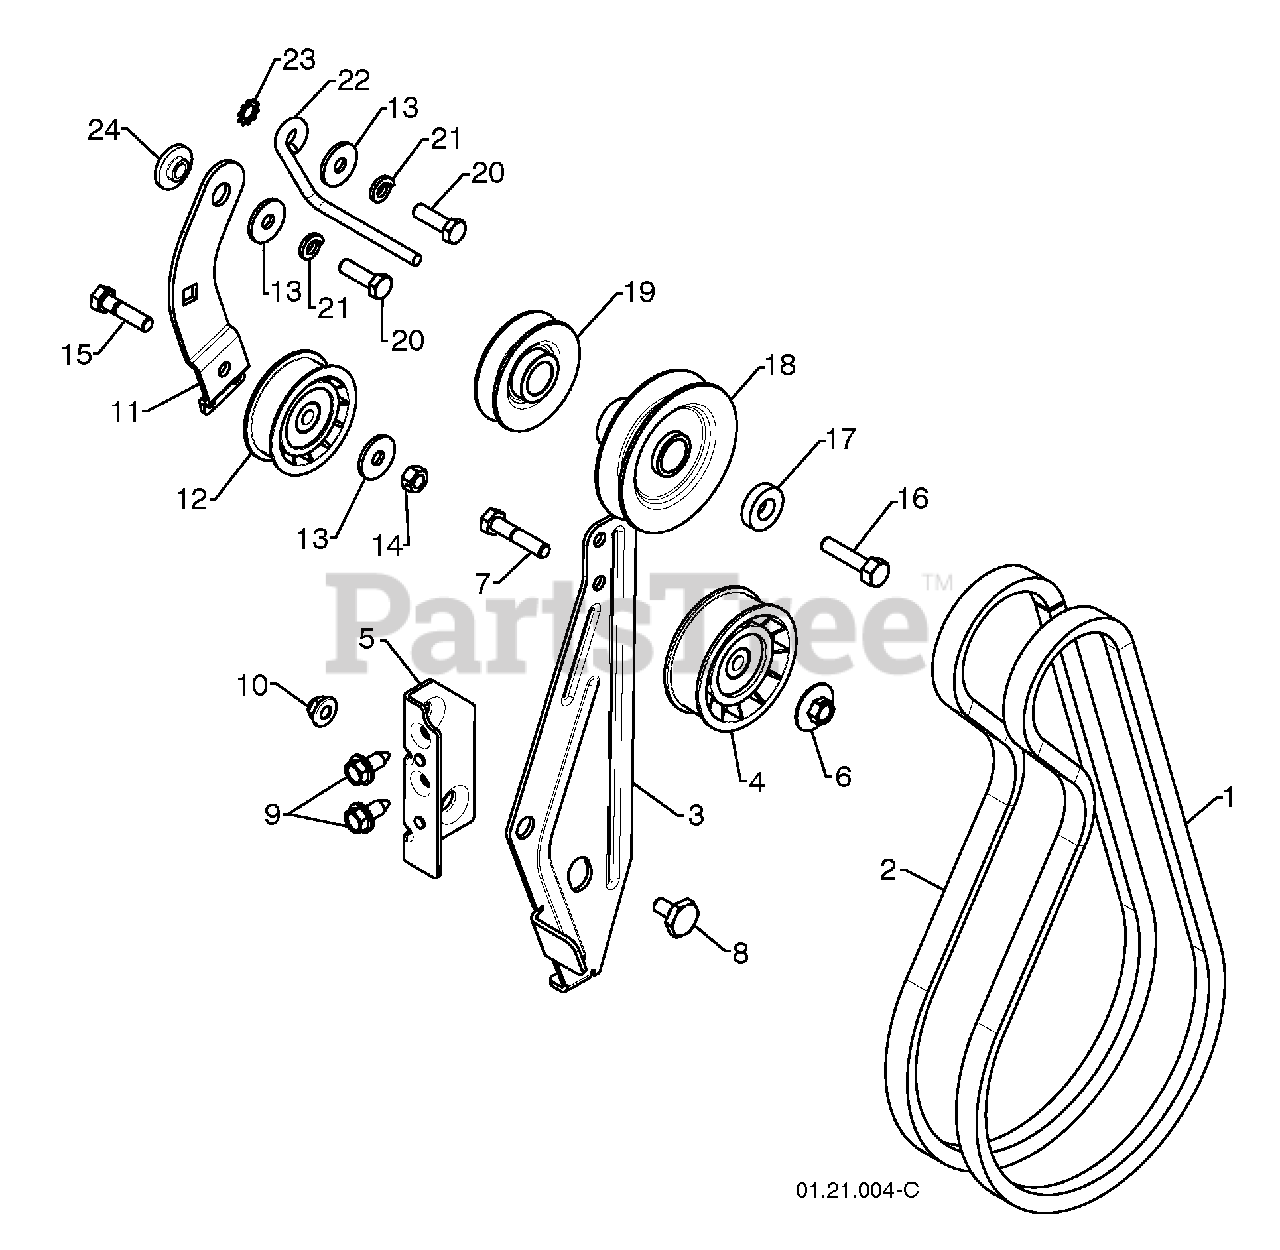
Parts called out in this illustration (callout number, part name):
1	IMPELLER BELT
2	TRACTION BELT
3	IDLER ARM BRACKET
4	IDLER PULLEY
5	IDLER ARM BRACKET
6	NUT 5/16-18
7	SCREW 5/16-18 X 1.50
8	SHOULDER BOLT 5/16-18 X .50
9	SCREW 5/16-18 X .625
10	NUT 5/16-18 NYLOCK
11	TRACTION IDLER BRACKET
12	TRACTION PULLEY
14	NUT 5/16-18
15	SCREW 5/16-18 X 1.25
16	SCREW 3/8-24 X 1.375
18	PULLEY ENG IMPELLER
19	PULLEY ENG TRACTION
20	SCREW 5/16-24 X 1.00
21	LOCKWASHER 5/16
22	BELT GUIDE
23	LOCKWASHER 5/16
24	IDLER BUSHING
